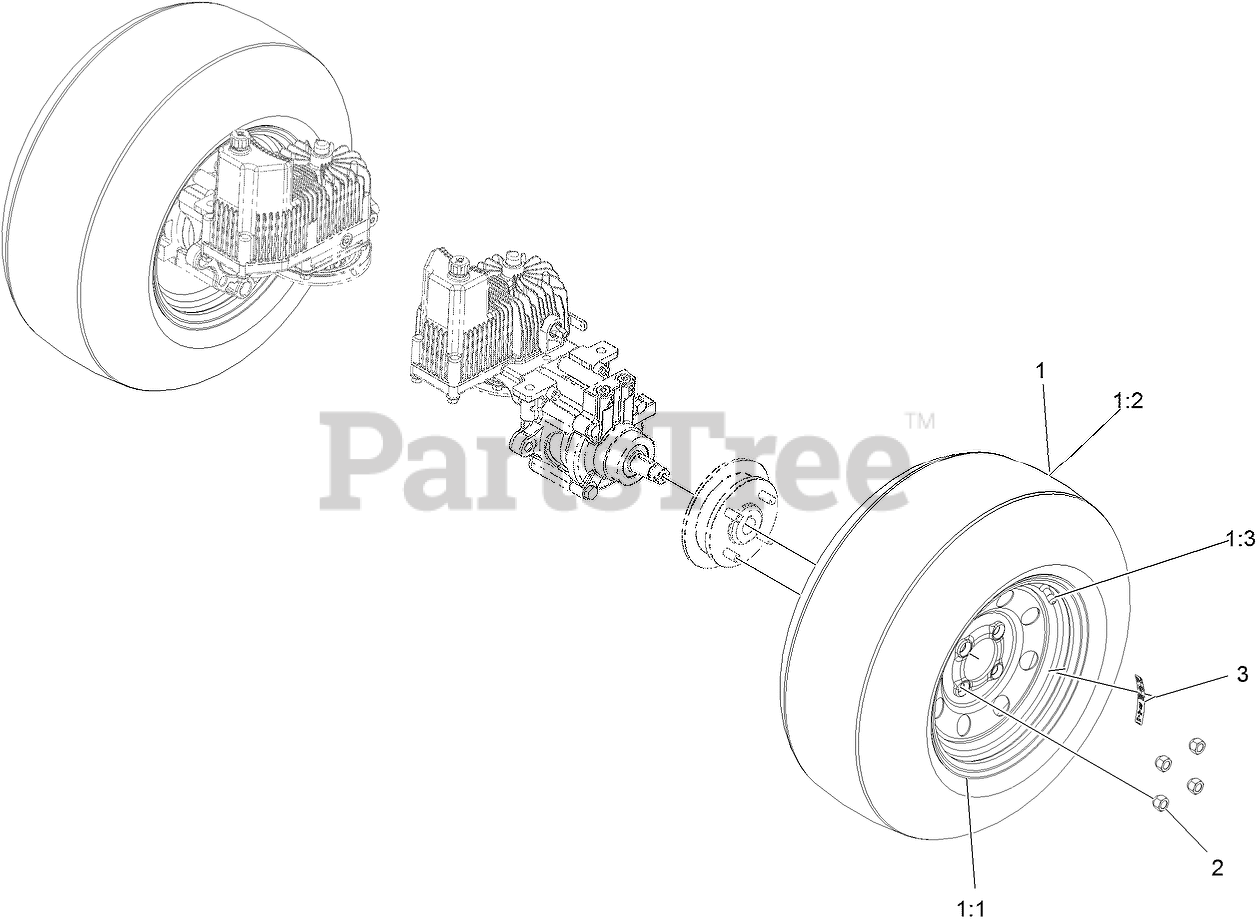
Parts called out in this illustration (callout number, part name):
1	WHEEL AND TIRE ASM
1:1	ASM, RIM
1:3	Stem-Valve
2	NUT-LUG
3	DECAL-TORQUE, WHEEL HUB LUG
